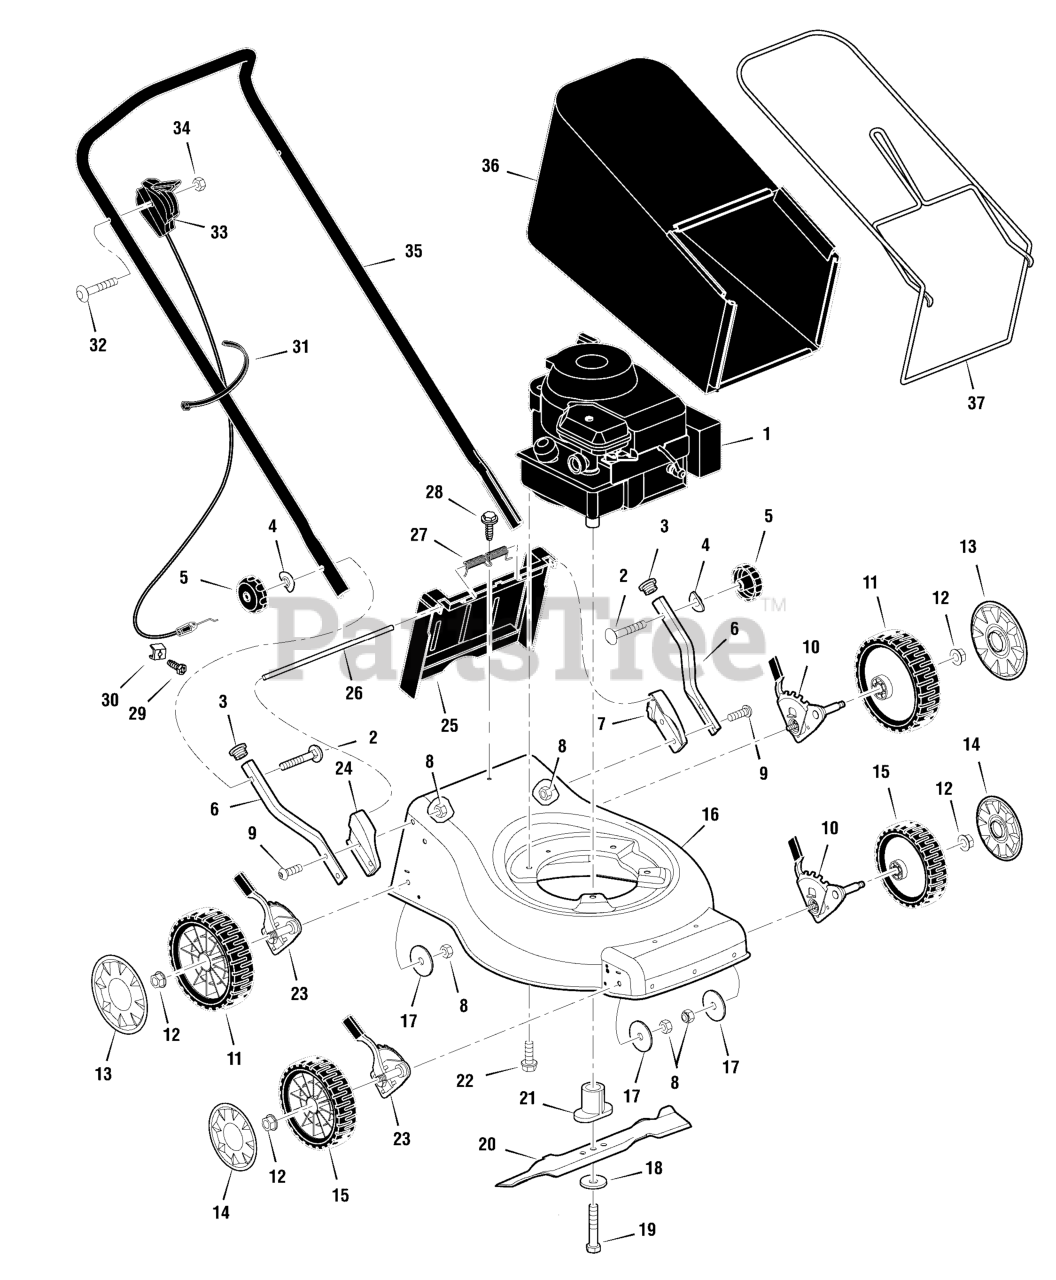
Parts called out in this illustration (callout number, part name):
1	ENGINE, Briggs & Stratton
3	PLUG, 7/8 inch
4	WASHER
6	HANDLE, Lower
7	BRACKET, Left Handle
8	LOCKNUT
9	BOLT, M8x1.25
10	ADJUSTER, Height, Left
11	WHEEL, 175 mm
12	LOCKNUT, 3/18-16
13	CAP, Hub, 7 inch
14	CAP, Hub, 6 inch
15	WHEEL, 150 mm
16	HOUSING, Mower
17	WASHER, Flat
18	WASHER, Belleville
19	BOLT
20	BLADE, 16 inch
21	ADAPTER, Blade
22	BOLT, Engine Mounting
23	ADJUSTER, Height, Right
24	BRACKET, Right Handle
25	DOOR, Rear
26	ROD, Rear Door
27	SPRING, Torsion
30	CLAMP, Cable
31	TIE, Cable
33	CONTROL, Throttle
34	LOCKNUT
35	HANDLE, Upper
36	CATCHER, Grass
37	FRAME ASSEMBLY
